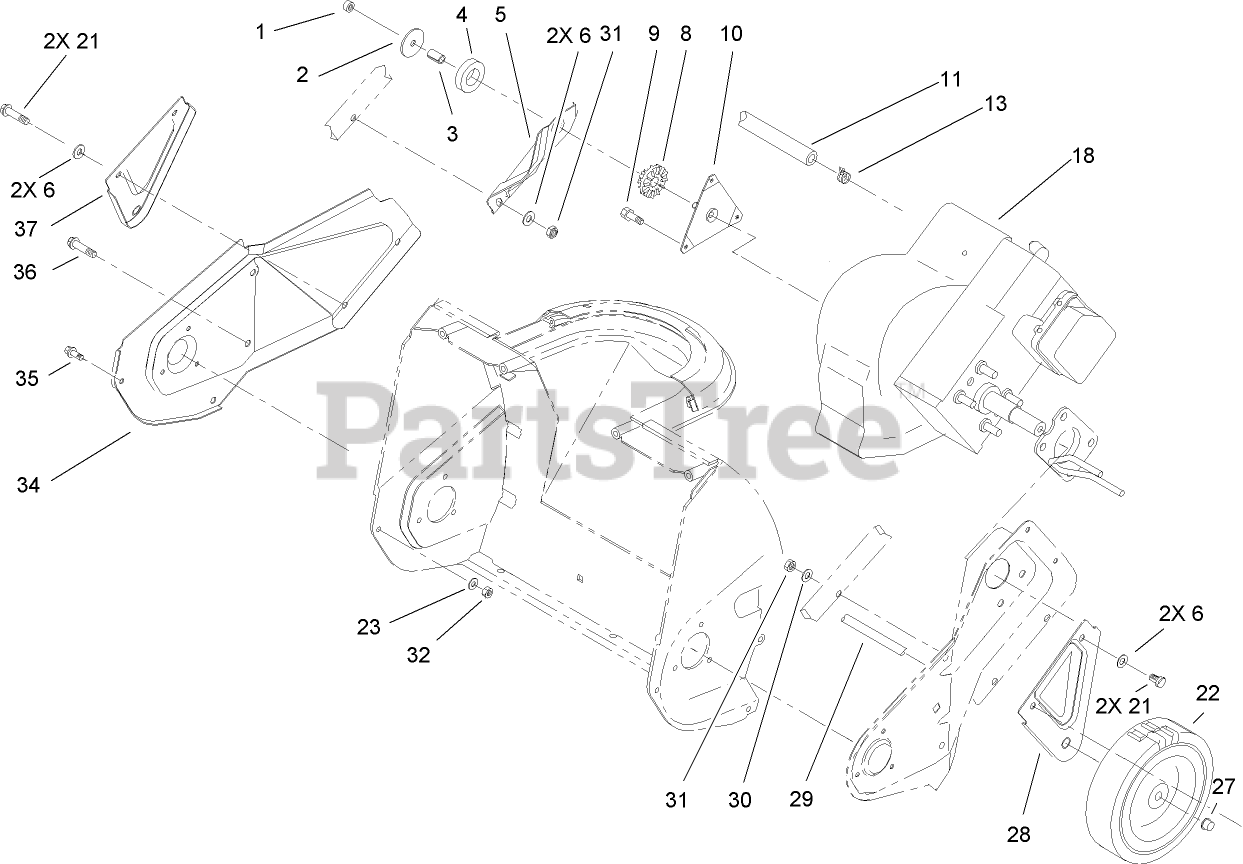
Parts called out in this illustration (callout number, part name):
1	NUT-LOCK, NI
3	SPACER-TUBULAR
4	RING-ISOLATOR
5	BRACKET-SUPPORT, ENGINE
6	WASHER-FLAT
8	BUSHING-ISOLATOR
9	SCREW
10	BRACKET AND STUD ASM
11	HOSE-FUEL
13	CLAMP-HOSE
21	SCREW-HH
22	WHEEL
23	WASHER-FLAT
27	NUT-PUSH
28	BRACKET-WHEEL, LH
29	AXLE SHAFT
30	WASHER
31	NUT-LOCK, NI
32	NUT-LOCK, NI
34	PLATE-SIDE, RH
36	SCREW-PLASTIC
37	BRACKET-WHEEL, RH
